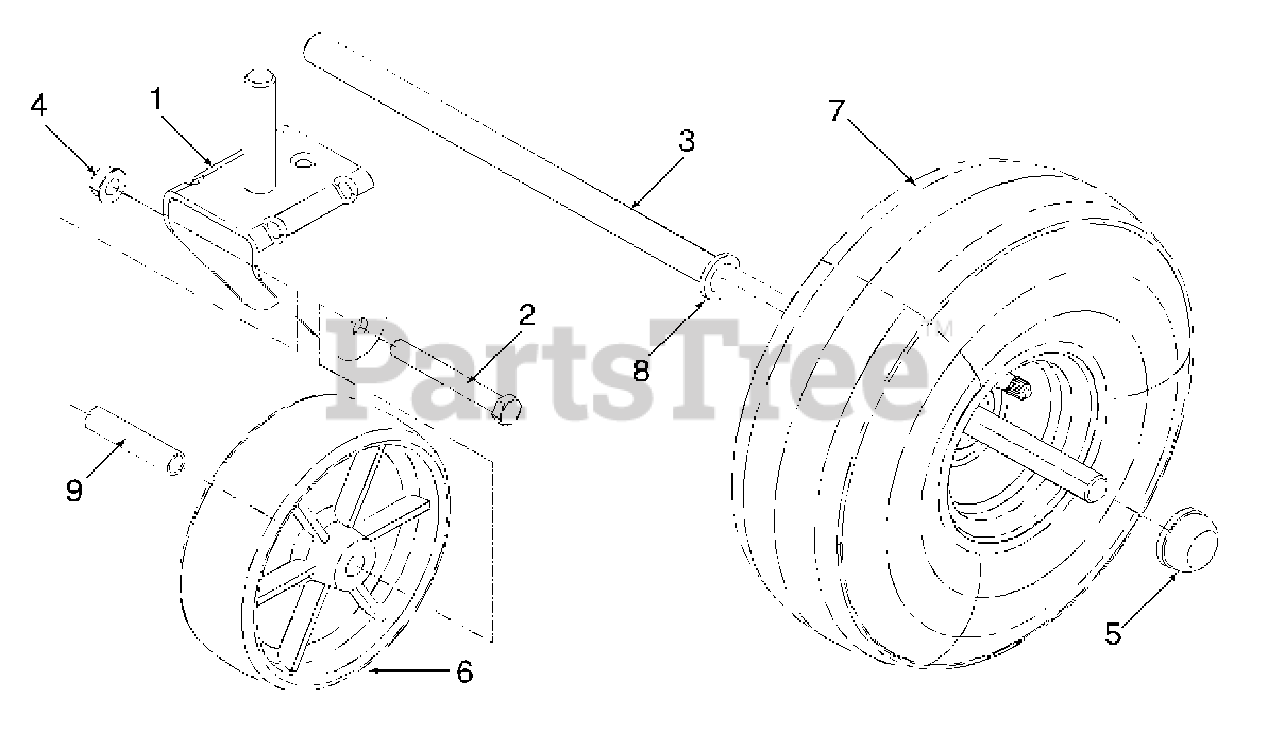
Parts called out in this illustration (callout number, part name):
1	Bracket Assembly, Pivot Wheel
2	Screw, Hex Cap, 3/8-16 x 3.0
3	Shaft, Rear Axle
4	Nut, Hex Flange Lock, 3/8-16
5	Push Cap
6	Wheel, 6.00 x 2.00
9	Spacer, .384 ID x .5 OD x 2.3 Lg
